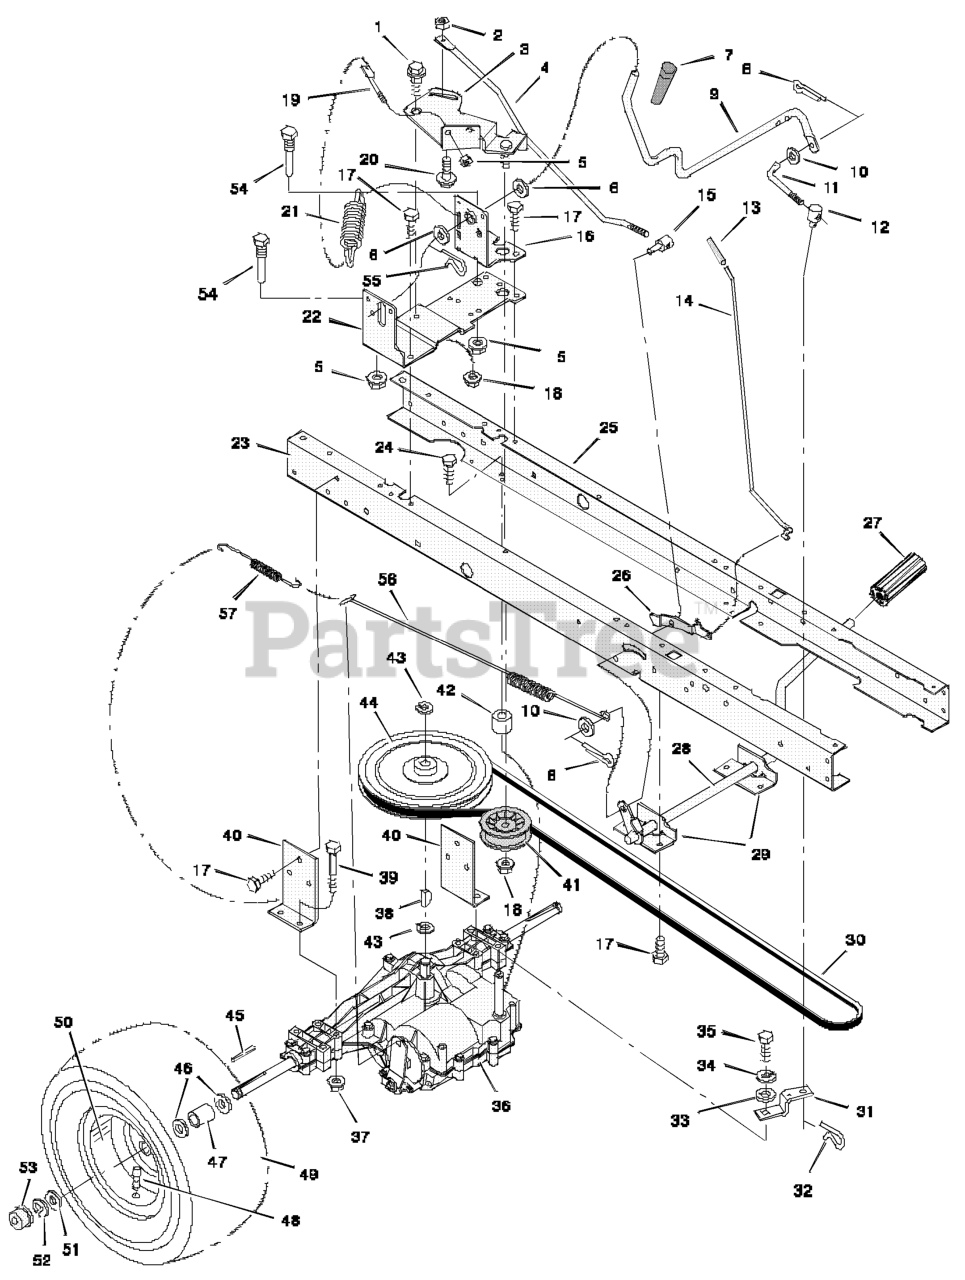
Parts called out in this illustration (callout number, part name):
1	Bolt, Shoulder
2	Nut, Hex
3	Arm, Idler
4	Rod, Clutch
5	Nut
6	Washer
7	Grip
8	Pin, Cotter
9	Lever, Shift
10	Washer
11	Link, Shift
12	Nut, Adjuster
14	Rod, Parking Brake
15	Nut, Adjuster
16	Bracket, Shift
18	Nut
20	Bolt, Shoulder
21	Spring, Extension
22	Bracket, Shifter
23	Frame, Right
25	Frame, Left
26	Latch, Parking Brake
27	Pedal
28	Lever, Brake/Clutch
29	Bracket, Pedal
30	Belt, Motion Drive
31	Yoke, Shift
32	Pin, Hair
34	Washer
36	Transaxle **
37	Nut
38	Key, Woodruff
40	Bracket, Transaxle
44	Pulley, Drive
45	Key, Square
47	Spacer, Transaxle
48	Stem, Valve
50	Wheel & Tire Assembly
53	Hub Cap
54	Guide, Belt
55	Pin, Hair
56	Spring, Extension
57	Spring, Extension
